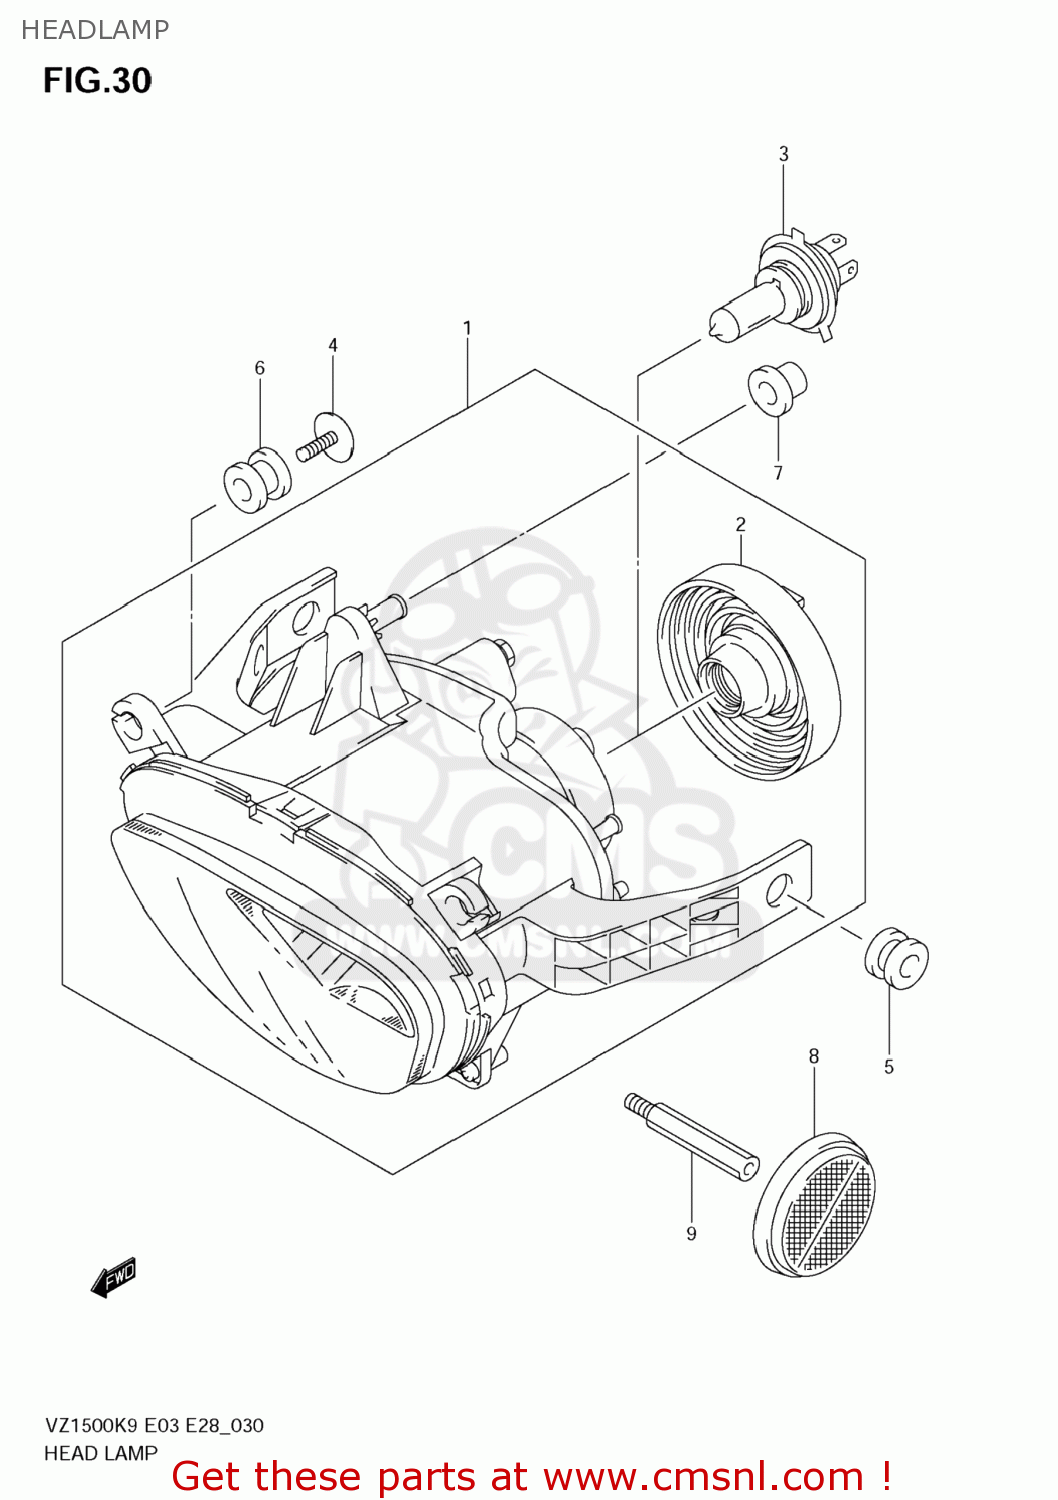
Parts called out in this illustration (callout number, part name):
1	HEADLAMP ASSY
2	COVER
3	BULB(12V60/55W,H4)
4	SCREW(5X15)
5	CUSHION
6	CUSHION
7	CUSHION
8	REFLECTOR,REFLEX
9	BOLT
